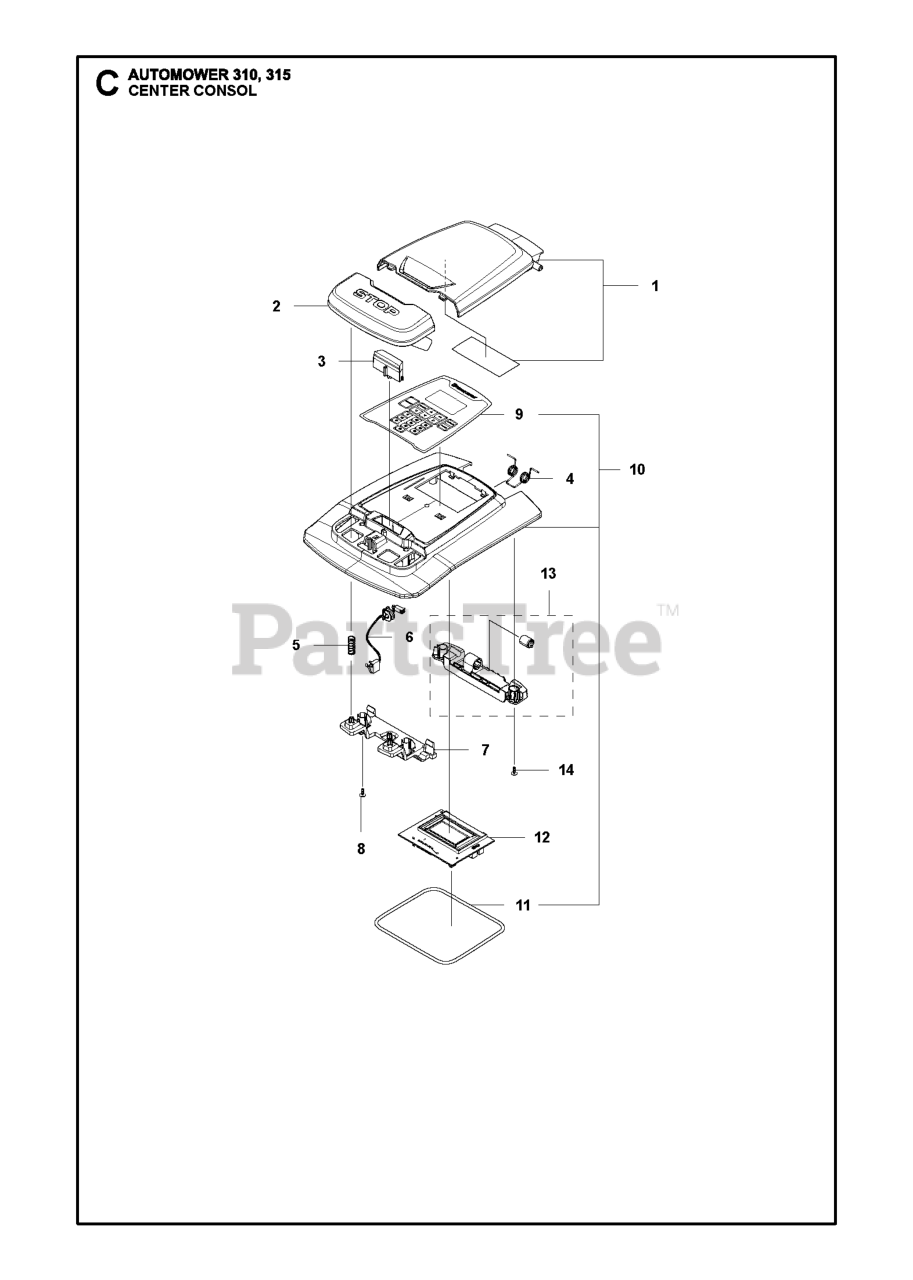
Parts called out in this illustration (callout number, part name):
1	CHASSIS LEFT
2	CHASSIS RIGHT
3	COVER CHASSIS
4	PUSH BUTTON
5	SPRING
7	COVER WIRING
8	LOCKING BUTTON
9	SCREW IHSCFT
10	RECOIL SPRING RECOIL SPRING RE
12	HANDLE HOLDER
13	SCREW
14	REAR HANDLE LEFT
15	REAR HANDLE RIGHT
16	SCREW
17	FRAME KEYPAD
18	BRACKET KEYPAD
19	THROTTLE CONTROL
